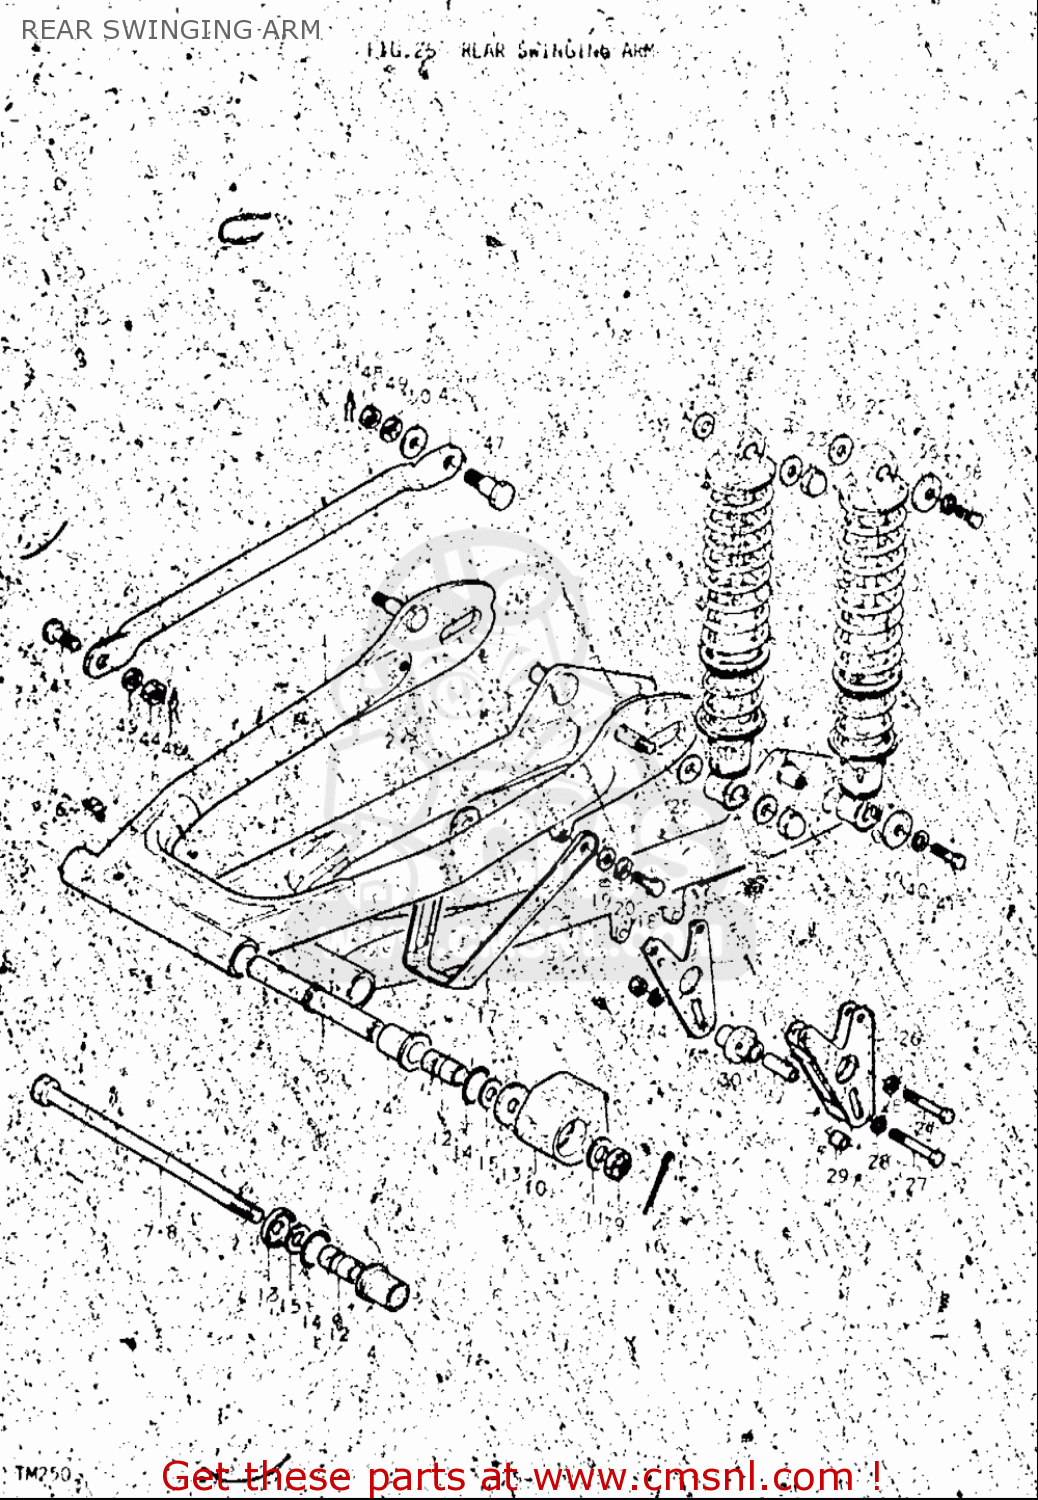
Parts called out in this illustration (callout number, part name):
4	BUSH
5	SPACER,SWING ARM,CENTER
6	NIPPLE,GREASE
9	NUT
10	BUFFER,CHAIN TOUCH DEFLECTOR
11	WASHER
12	SPACER
13	COVER
14	O RING(D:2,ID:24.5)
15	WASHER(12.5X24X2.3)
16	COTTER PIN
18	BOLT
19	WASHER
20	WASHER,LOCK
23	NUT
24	WASHER
25	WASHER (10.5X24X2.3)
27	BOLT
28	WASHER,LOCK
29	SPACER(6.5X12X6.9)
31	NUT (6MM)
32	SPACER
34	WASHER
35	WASHER
36	WASHER(6.5X24X1.6)
37	WASHER,LOCK
38	BOLT
39	WASHER
40	WASHER,LOCK
41	BOLT
43	BOLT(8X22.5)
44	NUT
45	WASHER,LOCK
46	CLIP
47	BOLT(10X32.5)
48	NUT
49	WASHER,LOCK
50	WASHER(12.5X24X1.6)
51	CLIP
